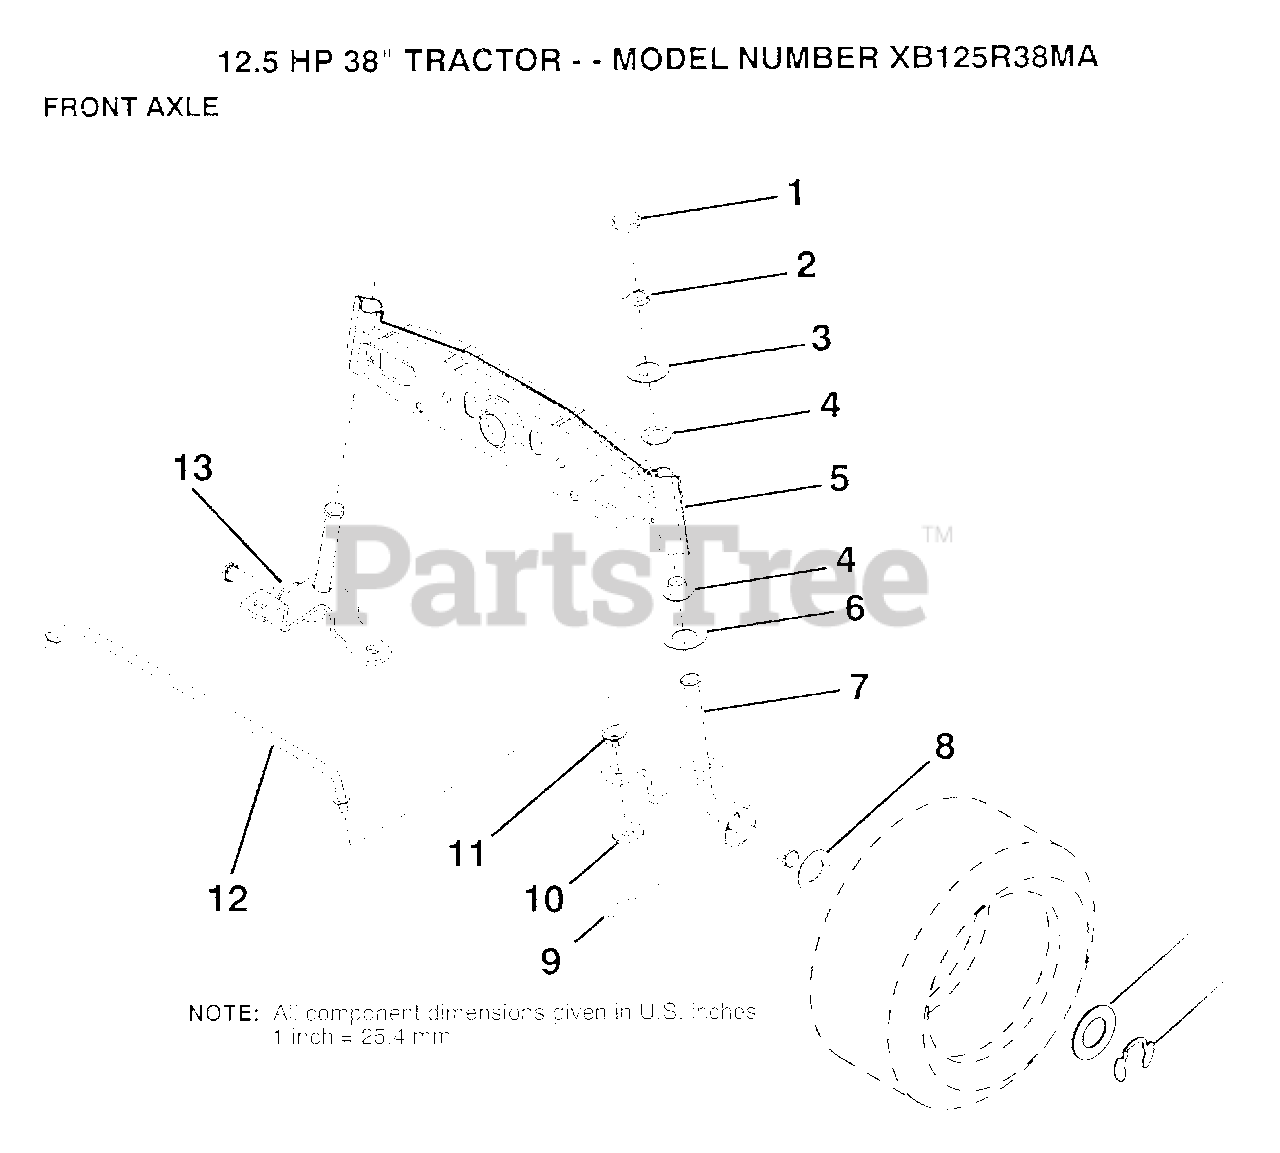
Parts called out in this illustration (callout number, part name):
1	CAP
2	RING
3	WASHER
4	NYLINER
5	AXLE FRONT
6	WASHER .T
7	SPINDLE RH
8	WASHER
9	COTTER PIN
10	WASHER
11	BUSHING.DRAGLINK
12	ROD TIE
13	SPINDLE LH
